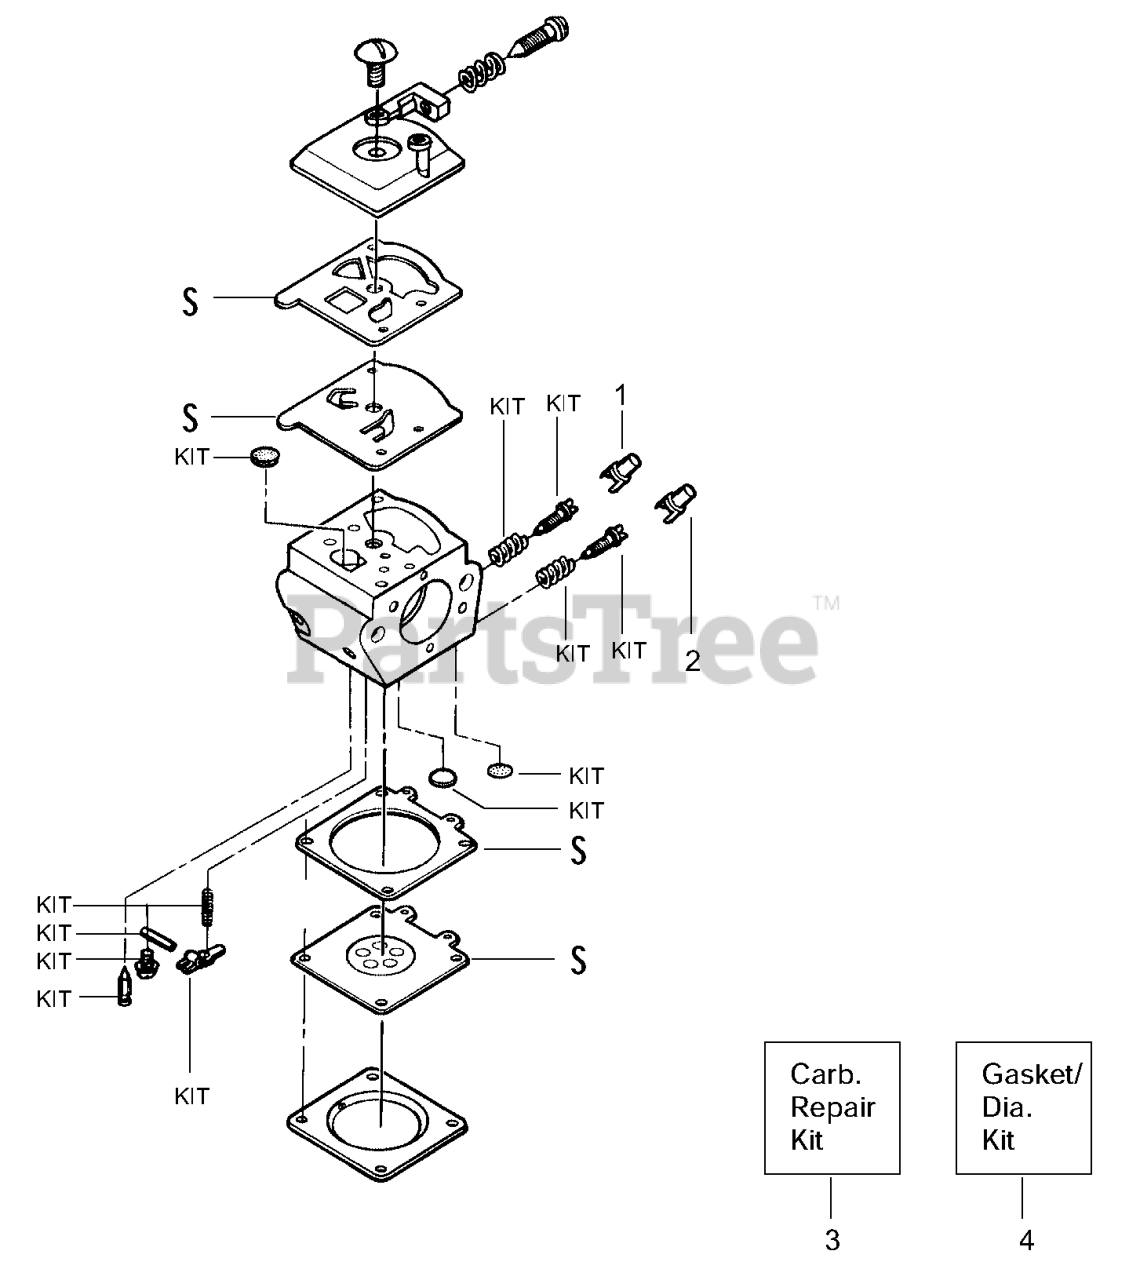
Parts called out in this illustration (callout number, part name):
1	LIMITER CAP-HIGH
2	LIMITER CAP-LOW
3	CARB REPAIR KIT
4	GASKET/DIAPHRAGM KIT
